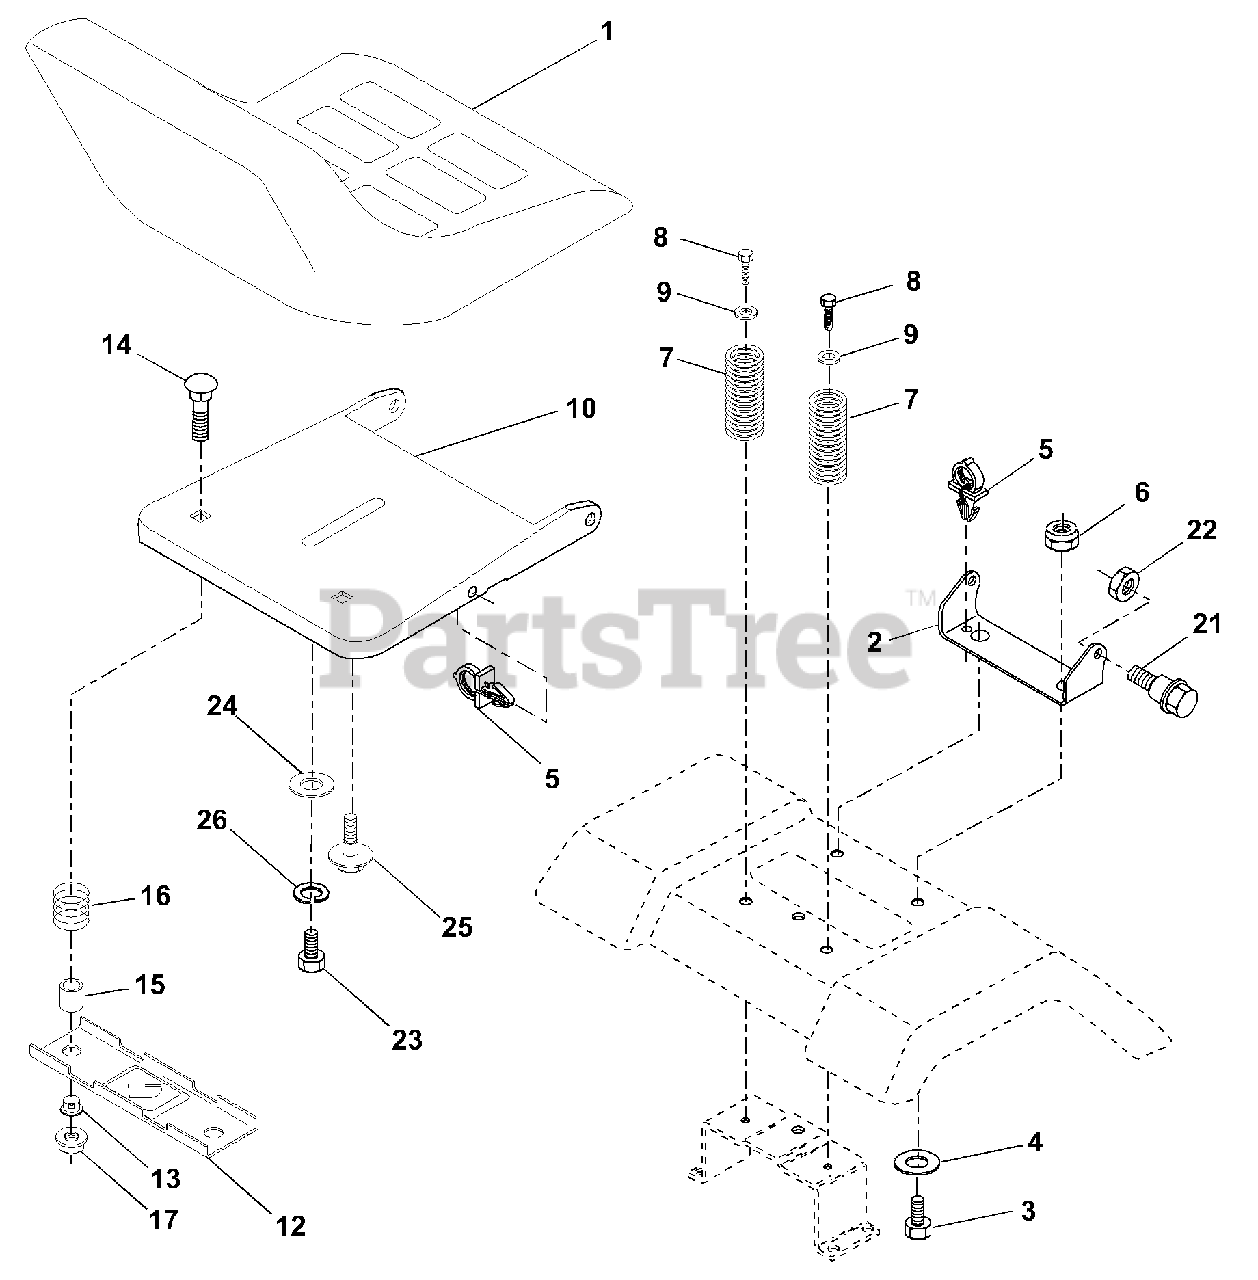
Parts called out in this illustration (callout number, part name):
1	Seat
2	Bracket Pnt Pivot Seat (blk)
3	Bolt
4	Washer 13/32 x 1 x 10 Ga
5	Clip Push-In Hinged
6	Nut
7	Spring Seat Cprsn 2 250 Blk Zi
8	Screw 3/8-16 x 1.5
9	Washer 13/32 x 1 x 14 Ga
10	Pan Pnt Seat (blk)
12	Bracket Pnt Mounting Switch
13	Bushing Snap Blk Nyl 50 Id
14	Bolt Rdhd Sht Nk 1/4-20 x 1-1/2
15	Spacer Split 28 x 96 Yel Zinc
16	Spring Cprsn 1 27 Blk Pnt
17	Nut Lock 1/4 Lge Flg Gr 5 Zinc
21	Bolt Shoulder 5/16-18 Unc Blkz-2A
22	Nut
23	Bolt Hex Black
24	Washer 17/32 x 1-3/16 x 12 Ga
25	Bolt Shoulder 5/16-18 x 62
26	Lockwasher
